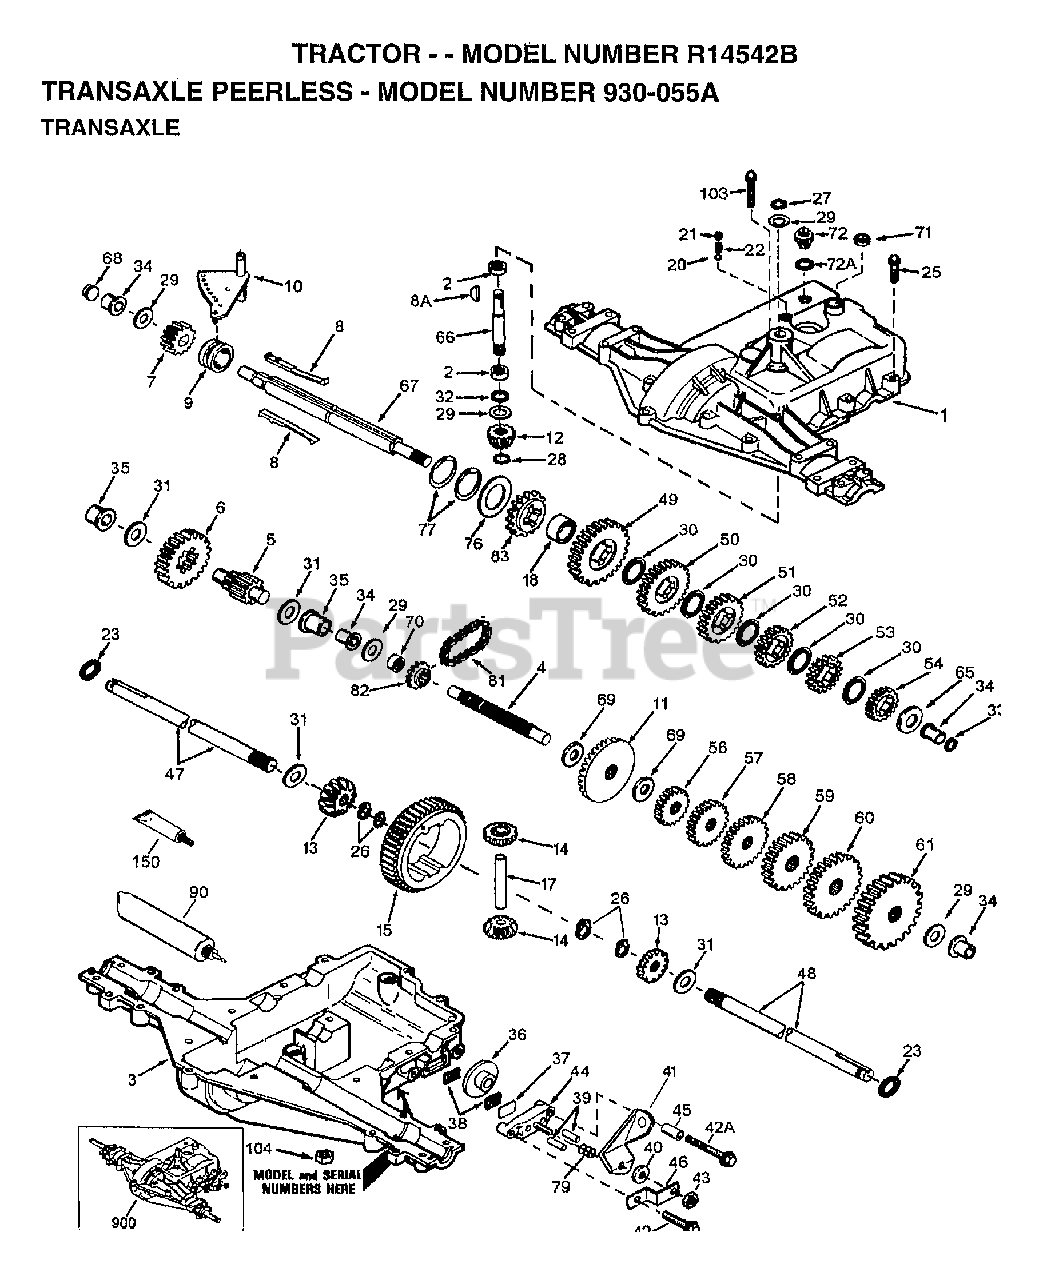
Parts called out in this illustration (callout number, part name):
1	TRANSAXLE COVER
2	BEARING, NEEDLE
3	TRANSAXLE CASE
4	SHAFT, COUNTER
5	OUTPUT SHAFT AND PINION
6	GEAR, OUTPUT
7	GEAR, SPUR, 15 TEETH
8A	KEY, WOODRUFF
9	COLLAR, SHIFTER
10	ROD & FORK ASSY, SHIFT
11	GEAR, BEVEL, 42 TEETH
12	BEVEL PINION, INPUT
13	GEAR, BEVEL
14	GEAR, BEVEL, PINION
18	SPACER, NEUTRAL
20	BALL STEEL, 5/16" DIA.
21	SCREW, 3/8-16 X 3/8"
25	SCREW, 1/4-20 X 1-1/4
26	RING RETAINER
27	RING, RETAINER
28	RETAINING RING
29	WASHER THRUST
30	WASHER THRUST
33	SEAL, SQUARE CUT
34	BUSHING, FLANGED
35	BUSHING, FLANGED
36	DISK, BRAKE
37	PLATE BRAKE PAD
41	BRAKE LEVER
42	SCREW, 1/4-20 X 1-1/4
42A	SCREW, 1/4-20 X 2-1/4
43	LOCKNUT 5/16-24
44	HOLDER BRAKE PAD
46	BRKT BRAKE LEVER
49	GEAR, SPUR, 37 TEETH
50	GEAR, SPUR, 35 TEETH
51	GEAR, SPUR, 30 TEETH
52	GEAR, SPUR, 25 TEETH
53	GEAR, SPUR, 22 TEETH
54	GEAR, SPUR, 19T
56	GEAR, SPUR, 12 TEETH
57	GEAR, SPUR, 15 TEETH
58	GEAR, SPUR, 20 TEETH
59	GEAR, SPUR, 25 TEETH
60	GEAR, SPUR, 28 TEETH
61	GEAR, SPUR, 31 TEETH
65	WASHER, THRUST
66	SHAFT, INPUT
67	SHAFT, BRAKE, 4 KEYED
69	WASHER THRUST
71	SEAL SQUARE CUT
72	THREADED PLUG 9/16-18
76	WASHER, THRUST
77	INVERTED RETAINING RING
81	CHAIN, ROLLER
82	SPROCKET 9T
83	SPROCKET 18T (REV)
90	GREASE BENTONITE, 32 OZ.
150	GASKET ELIMINATOR
900	REPLACEMENT TRANSAXLE
